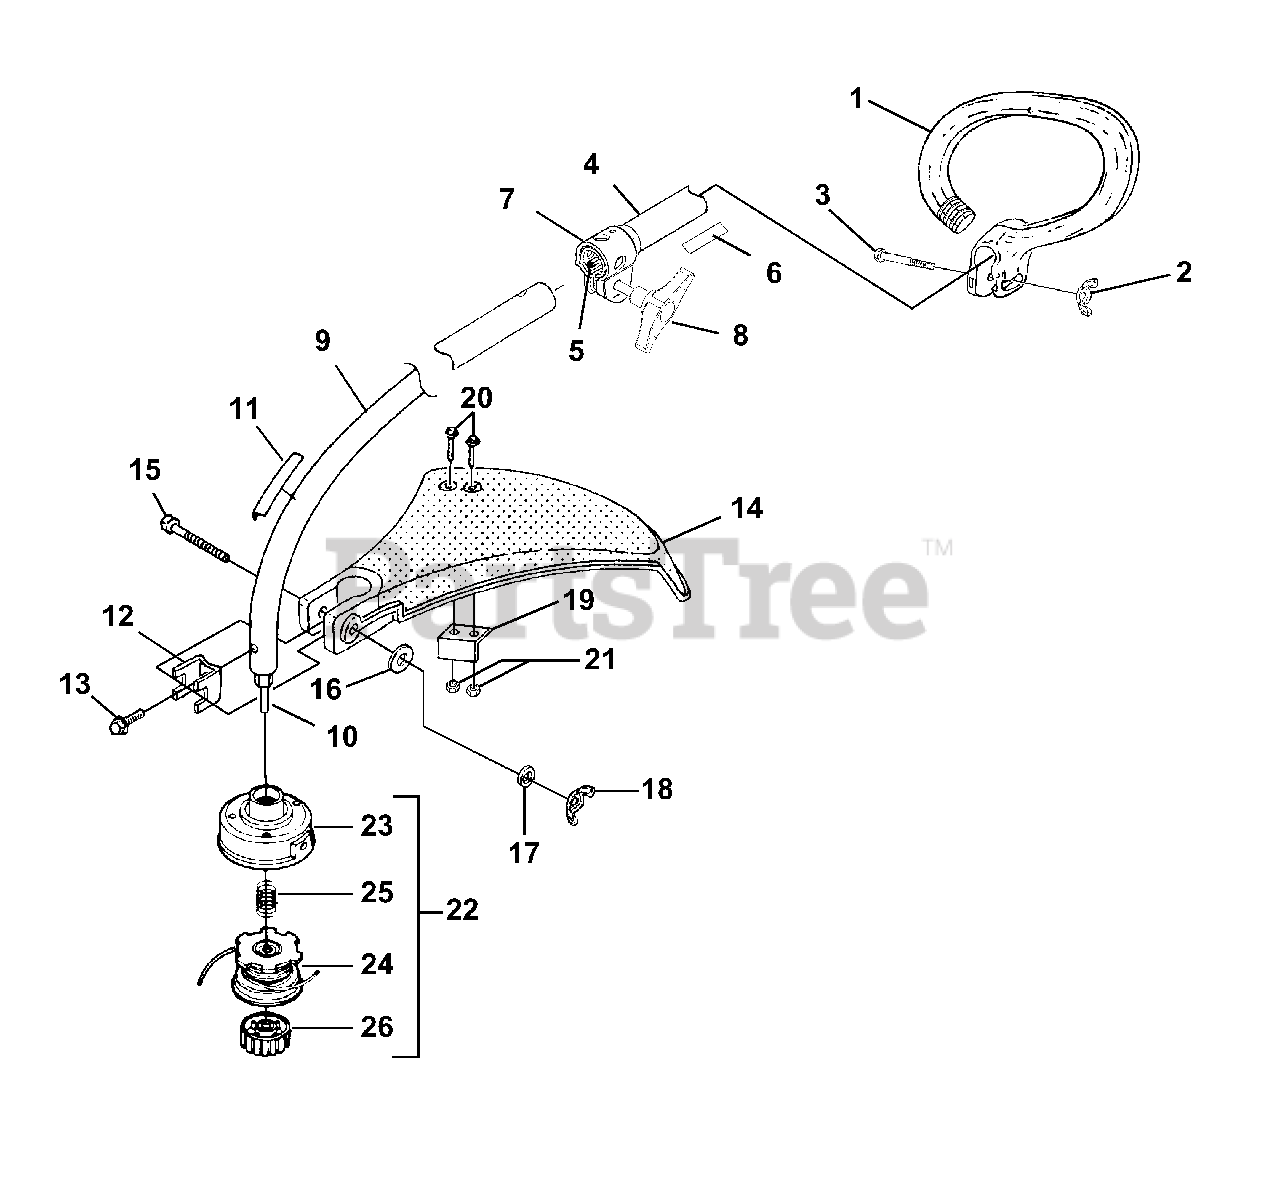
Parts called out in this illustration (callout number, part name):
1	HANDLE-Anti-Vibe
2	NUT-Wing, Washer Faced (1/4-20)
3	SCREW-Cap Hex Hd. (1/4-20 x 2")
4	DRIVESHAFT ASSY. (Upper)
5	FLEXSHAFT w/Collar & Liner
6	DECAL-Warning
7	COUPLER ASSEMBLY
8	KNOB
9	DRIVESHAFT HOUSING (Lower)
10	SHAFT-Flex
11	DECAL-Warning
12	CLAMP
13	SCREW-Sems Hex (10-24 X 3/8")
14	DEFLECTOR & BLADE KIT (55 Deg.)
15	SCREW-Cap Hex Hd. (1/4-20 X 2")
16	WASHER-Flat (1/4")
17	WASHER-Lock (1/4")
18	NUT-Wing, Washer Faced (1/4-20)
19	BLADE-Cut-Off
20	SCREW-Mech. Hex Hd. (10-24 X 7/8")
21	NUT-Hex (10-24)
22	STRINGHEAD-Complete (.095")
23	HOUSING & EYELET (Dual Line)
24	SPOOL & STRING (.095")
25	SPRING-Compression
26	RETAINER-Spool (R.H. Thread, Black)
